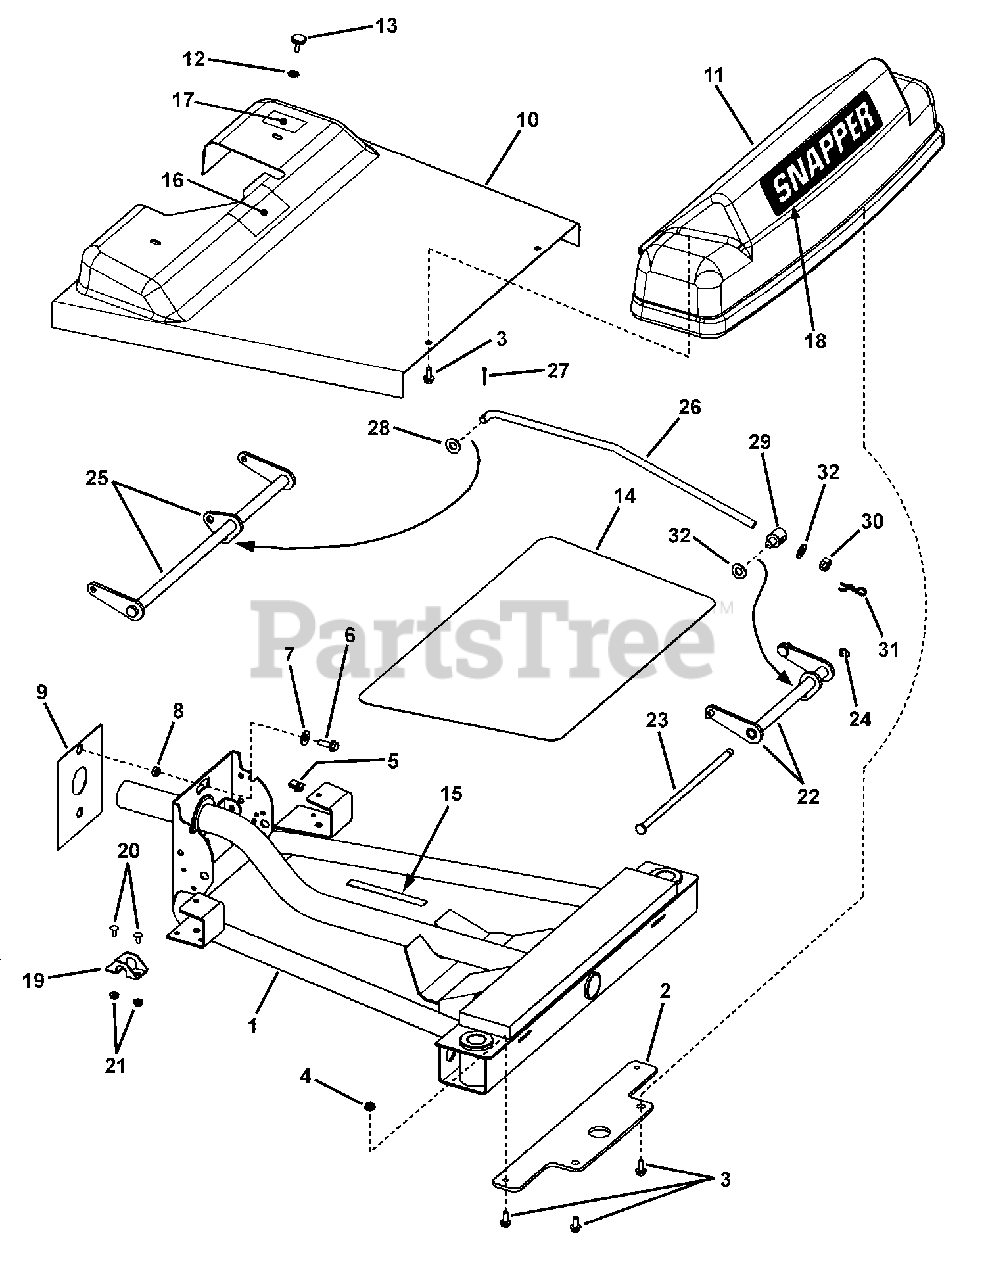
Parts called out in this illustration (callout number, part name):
1	WELDMENT, Front Frame Series #3
2	PLATE, Footrest Support
3	BOLT, 5/16-18 x 3/4" Hex Flange Lock
4	NUT, 5/16-18 Hex Flange Lock, GR 5
5	FASTENER, "U" Type
6	SCREW, 3/8-16 x 1" Hex Washer Self-tap
7	WASHER, 3/8" FLAT (wide)
8	SPACER, Front Frame Pivot
9	PLATE, Front Frame Slip
10	FLOOR PAN, HOZ
11	FOOTREST, HOZ
12	WASHER, 1/4" Internal/External Lock
13	KNOB (1/4-20 thread)
14	MAT, Floor
15	PAD, Floor Board Support
16	DECAL, Warning, Read Manuals & Instructions
17	DECAL, Deck Height
18	DECAL, SNAPPER (14.56" long)
19	BRACKET, Saddle- Front
20	BOLT, 1/4-20 x 5/8" Short Neck Carriage, GR 5
21	NUT, 1/4-20 Hex Flange Lock
22	WELDMENT, Front Lift, 48
23	ROD, Deck Support
24	RING, .438 External Retaining
25	WELDMENT, Rear Lift
26	TIMING ROD (1/2-13 thread)
27	COTTER PIN, 1/8 x 1"
28	WASHER, 1/2" Flat
29	SWIVEL, .50 Thru Hole
30	NUT, 1/2-13 Hex Center Lock, GR 5
31	HAIR PIN, 1/8" Dia. x 1/2"
32	WASHER, 1/2" SAE Flat
